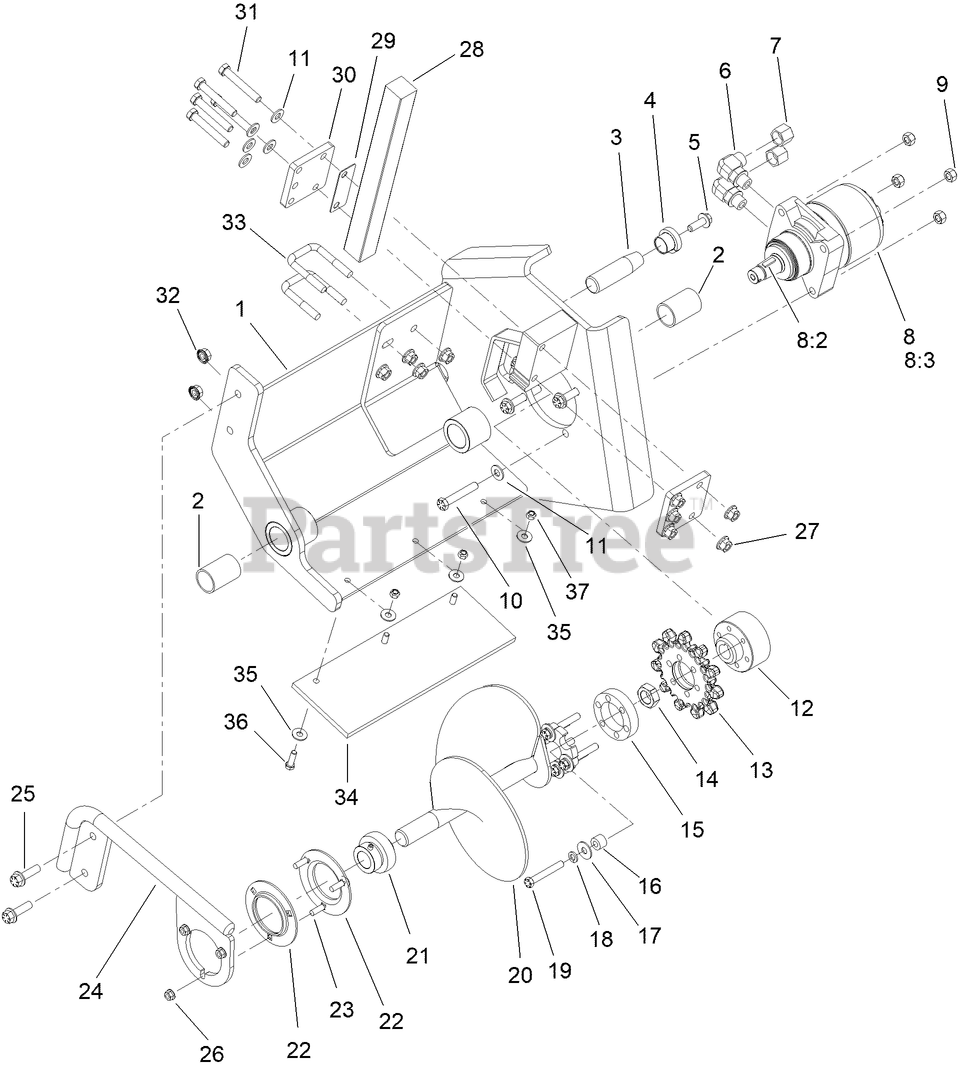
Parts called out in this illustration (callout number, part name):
1	AUGER SUPPORT
2	COMPOSITION BUSHING
3	TAPERED PIN (4.50 X 1.25)
4	TAPERED INSERT (1.25")
5	SCREW-HFH
6	CONNECTOR (10S-10O90)
8	MOTOR-WHEEL, RH
8:2	KEY-WOODRUFF
8:3	SEAL KIT
9	LOCKNUT
10	SCREW-HH
11	WASHER-FLAT
12	DRIVE HUB
13	SPROCKET 11 TOOTH 35K
14	NUT-LOCK
15	AUGER BUSHING SPACER
16	BUSHING
17	WASHER-FLAT
18	WASHER-LOCK
19	SCREW-HH
20	SPOILS AUGER - BLACK
21	BALL BEARING - MAINT. FREE (1.25)
22	FLANGETTE (3-BOLT, L/ZERK)
23	SCREW-CARR
24	AUGER SUPPORT
25	SCREW-HHF
26	NUT-HHF, WHIZ
27	NUT-LOCK
28	PIVOT STUB
29	PIVOT SHIM
30	CLAMP PLATE
31	SCREW-HH
32	NUT-HHF, WHIZ
33	U-BOLT 2 INCH SQUARE
34	FLAP-SPOILS
35	WASHER-FLAT
36	SCREW-HH
37	NUT-LOCK, NI
